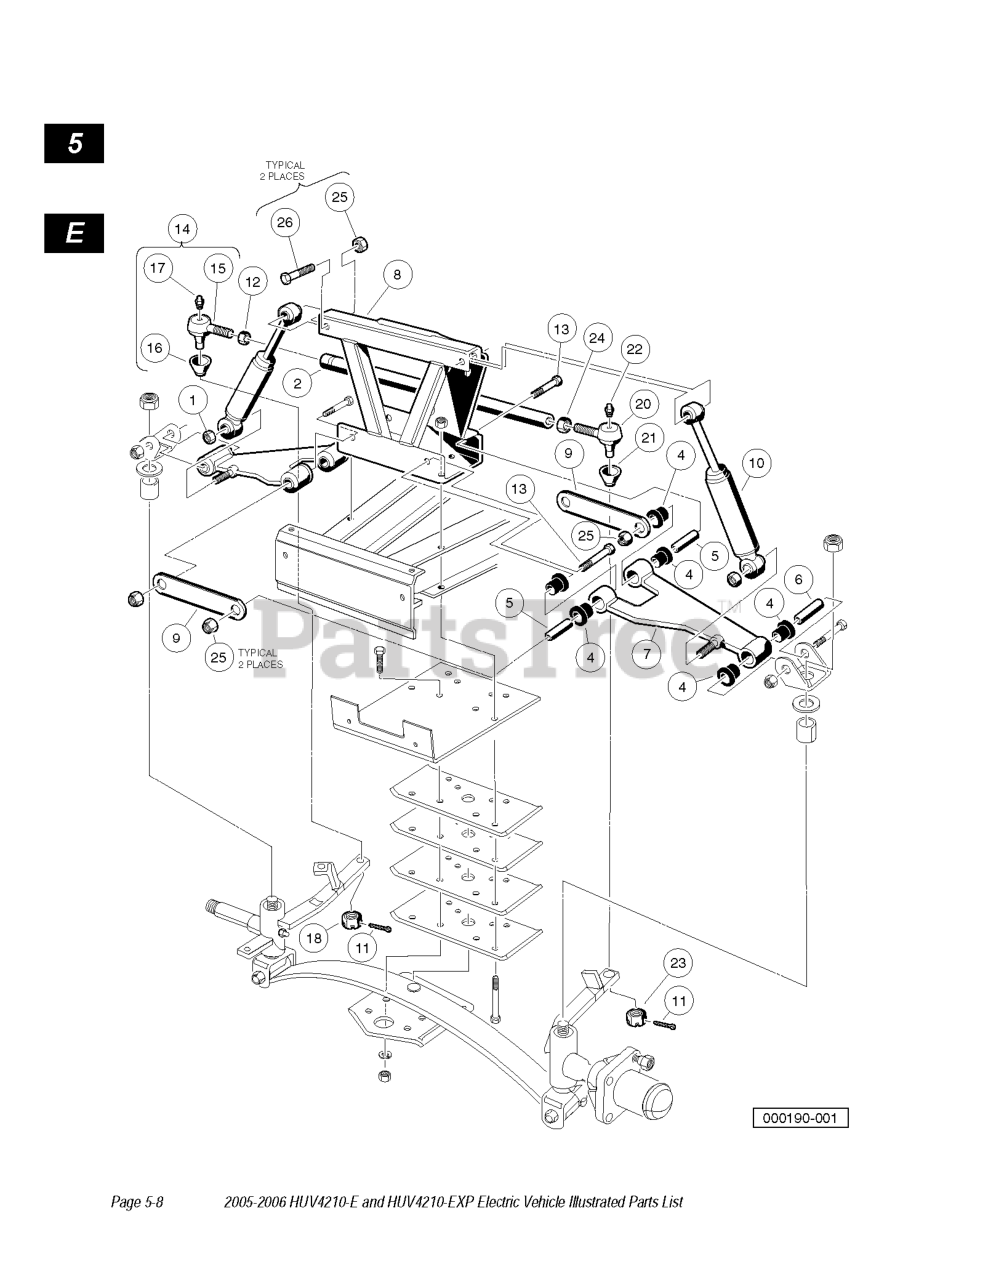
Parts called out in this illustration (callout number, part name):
1	LOCKNUT, DIMPLED
3	DELTA A PLATE SUB ASSEMBLY
4	BUSHING, URETHANE
5	SLEEVE, DELTA INNER
6	SLEEVE, DELTA OUTER
8	ASM, DELTA SHOCK & GEAR SUPPOR
9	A PLATE STRAP
10	SHOCK ABSORBER, FRONT, COMMON
11	PIN,CUT COTTER
12	NUT, 1/2-20 HEX
13	SCREW, 3/8-16 X 2.25 HX HD CAP
14	BALL JOINT, RH
16	SEAL, VERTICAL SOCKET DUST
17	FITTING, 1/4-28 THRD FRM GREAS
18	NUT, 3/8-24 UNF HEX THICK SLOT
19	BALL JOINT, LH
21	SEAL, VERTICAL SOCKET DUST
22	FITTING, 1/4-28 THRD FRM GREAS
23	NUT, 3/8-24 UNF HEX THICK SLOT
24	NUT, 1/2-20 HEX
25	LOCKNUT, 3/8-16 HEX
26	BOLT, 3/8-16 X 1.75 HEX
